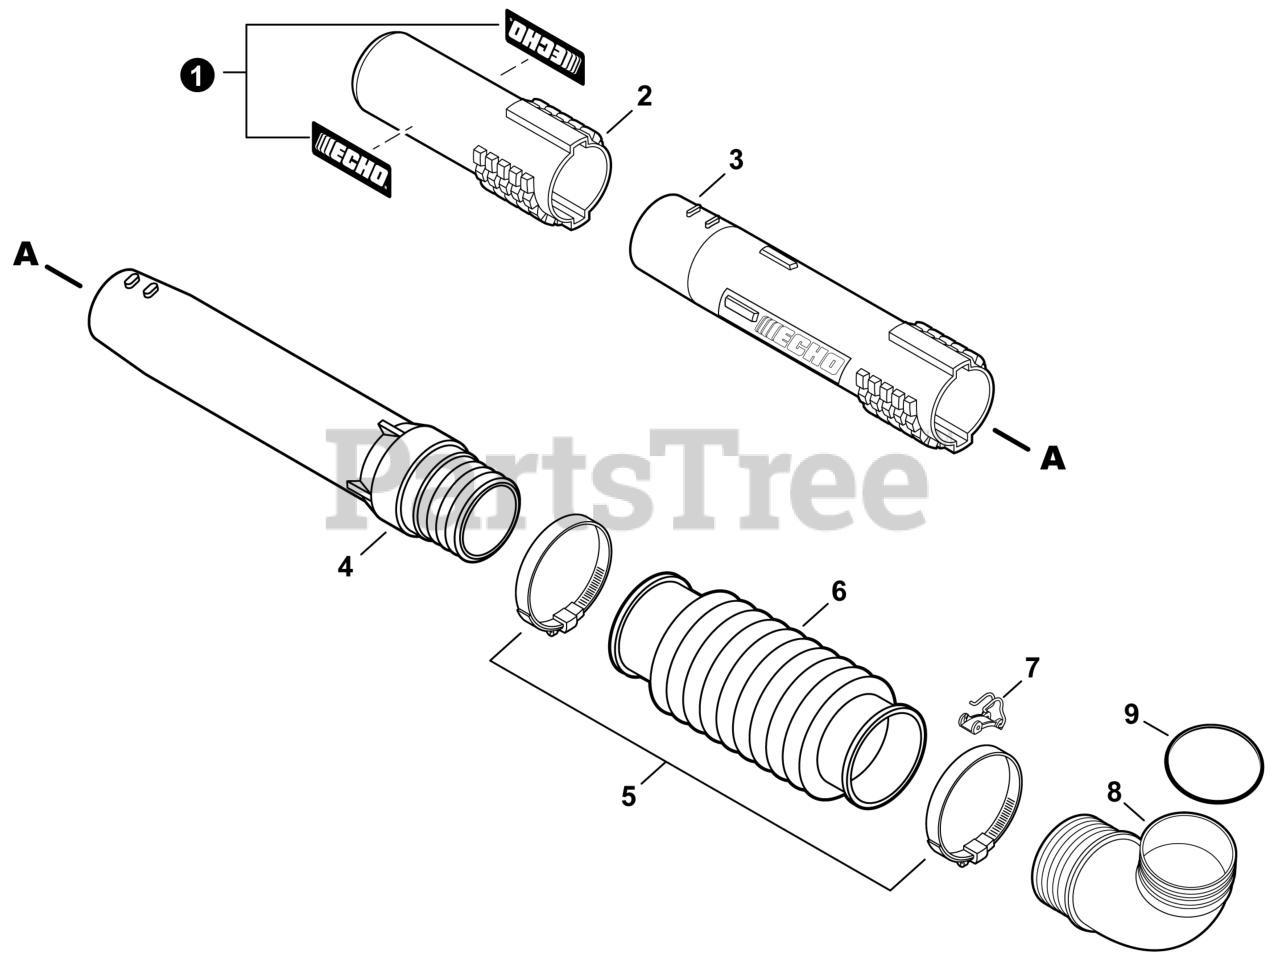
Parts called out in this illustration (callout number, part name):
1	LABEL - ECHO
2	TUBE, BLOWER - NOZZLE
3	TUBE, BLOWER - STRAIGHT
4	TUBE, BLOWER - SWIVEL
5	CLAMP - BAND 78 MM / 103 MM
6	TUBE, BLOWER - FLEXIBLE
7	CLIP, CABLE
8	TUBE, BLOWER - ELBOW
